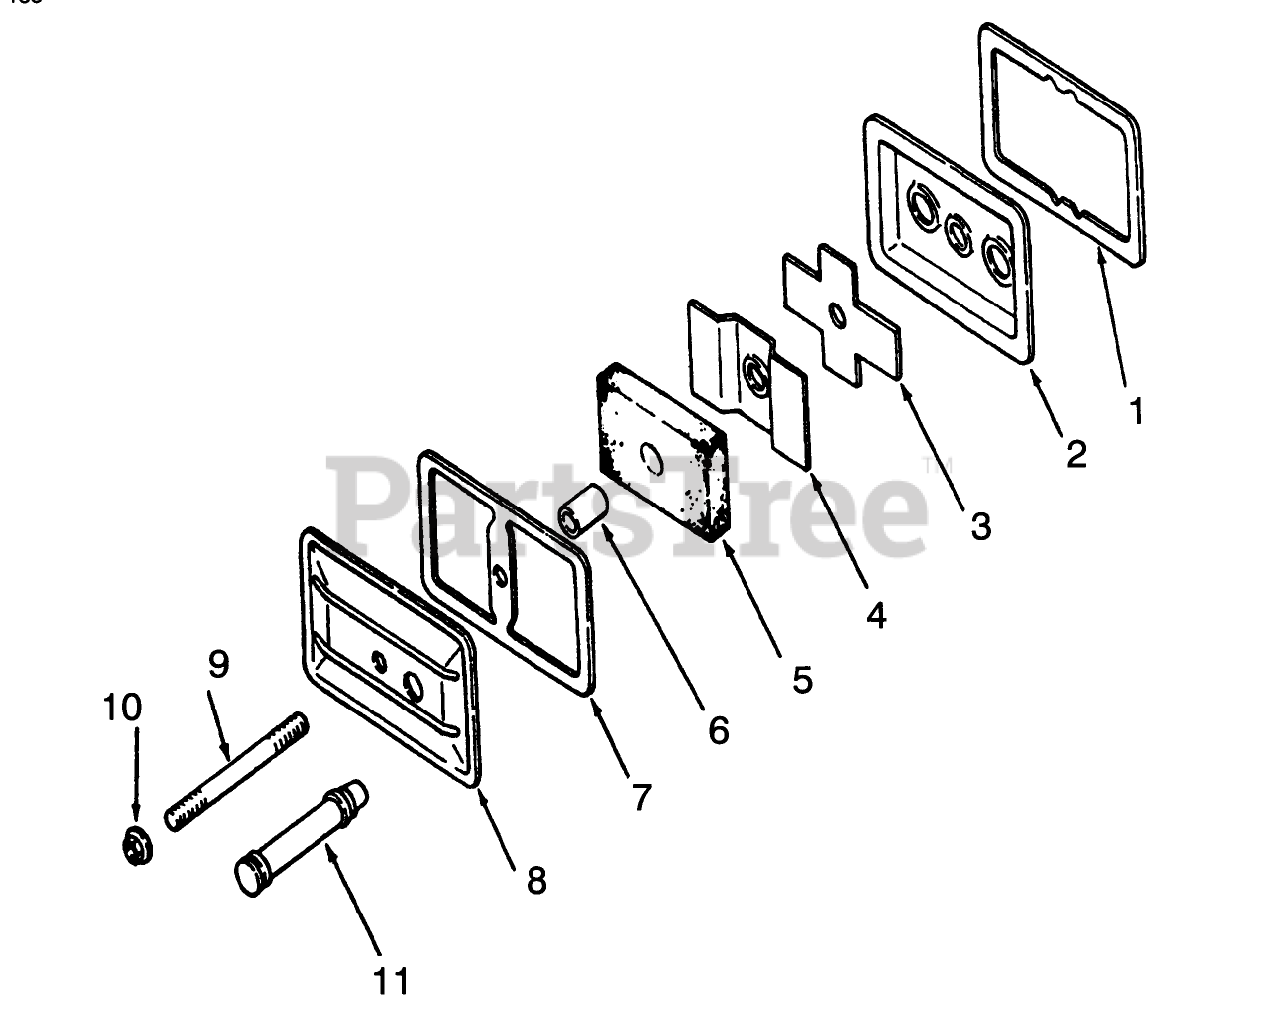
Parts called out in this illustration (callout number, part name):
1	KOHLER 235048
2	KOHLER 235631
3	KOHLER 235047
4	KOHLER 270146
5	KOHLER 47-050-01
6	KOHLER 231032
7	KOHLER 275144
8	KOHLER 47-096-01
9	KOHLER 275220
10	KOHLER X-799-1
11	KOHLER 47-326-03
